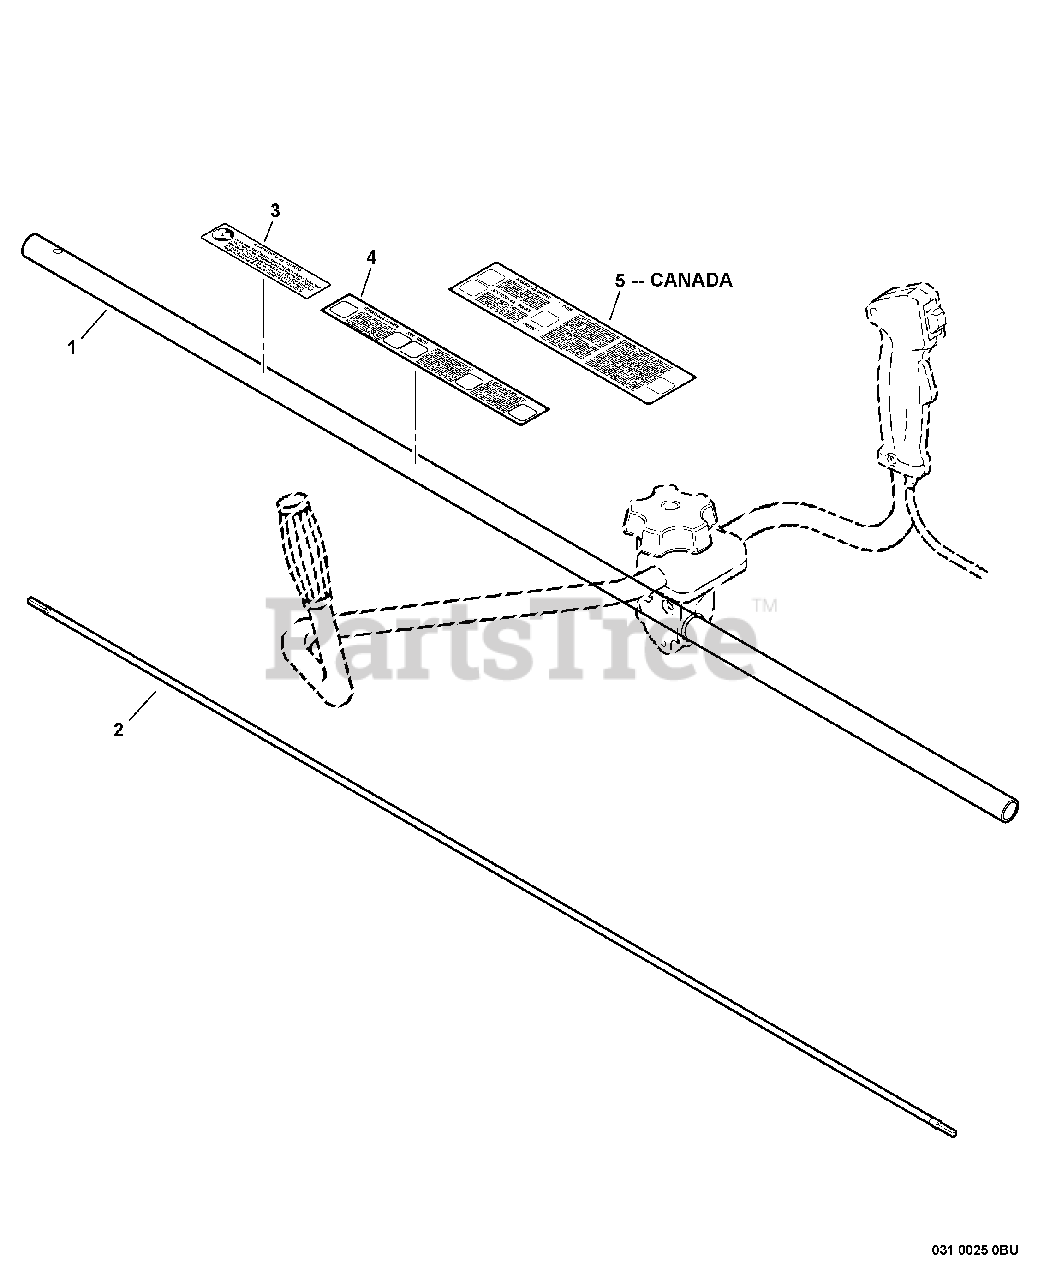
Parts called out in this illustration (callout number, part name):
1	PIPE, MAIN
2	DRIVESHAFT - SOLID
3	LABEL - CAUTION -- SPANISH
4	LABEL - CAUTION
5	LABEL - CAUTION
